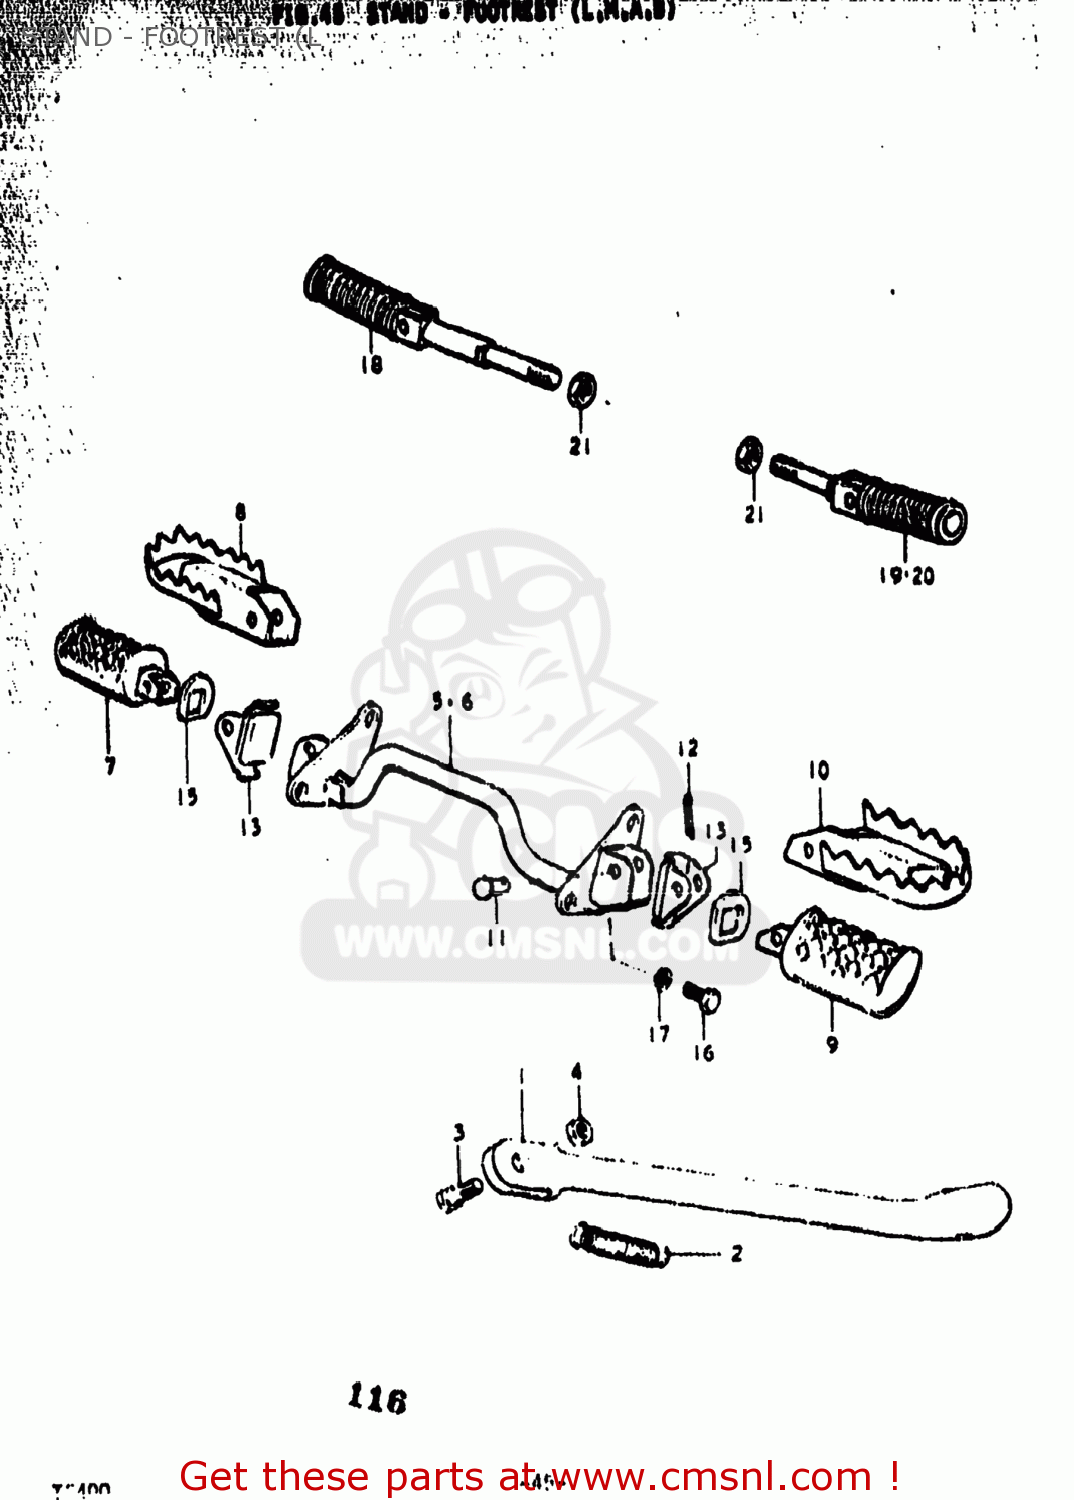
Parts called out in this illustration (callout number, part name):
1	STAND,SIDE
2	SPRING
3	BOLT(10X30)
4	NUT
5	BAR,FRONT FOOTREST
6	BAR,FRONT FOOTREST
7	RUBBER,FOOTREST,RIGHT
8	RUBBER,FOOTREST,RIGHT
9	RUBBER,FOOTREST,LEFT
10	RUBBER,FOOTREST,LEFT
11	PIN
12	PIN
13	CUSHION,FRONT FOOTREST
14	SPRING
15	WASHER
16	BOLT
17	WASHER,LOCK,8.
18	FOOTREST ASSEMBLY,PILLION
19	FOOTREST ASSY,PILLION
20	FOOTREST ASSEMBLY,REAR
21	NUT
